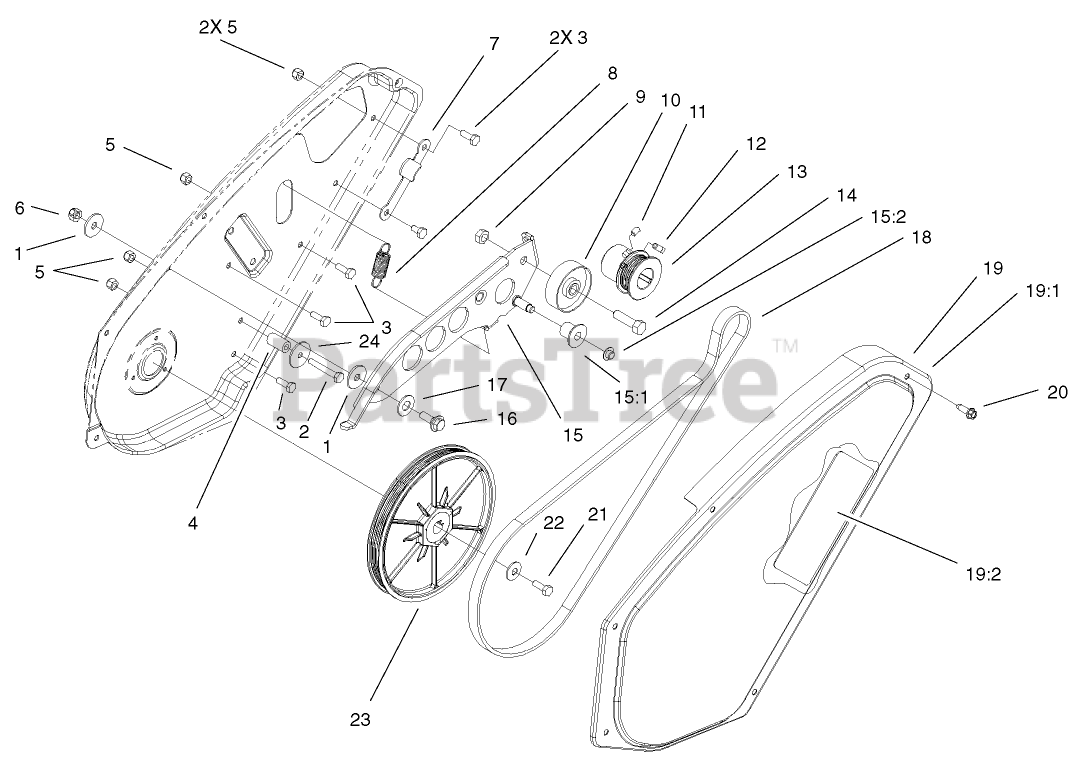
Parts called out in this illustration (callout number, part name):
1	WASHER-PIVOT
2	SCREW-HH
3	SCREW-HH
4	SLEEVE-GUIDE, BELT
5	NUT-LOCK, NI
6	NUT-LOCK, NI
7	BELT-GUIDE
8	SPRING
9	NUT-LOCK, CONE
10	PULLEY-IDLER
11	SCREW-HSH
12	SCREW-SQH
13	PULLEY
14	SCREW-HH
15	BRAKE-ARM
15:1	ROLLER-BRAKE
15:2	NUT-PUSH
16	SCREW-SHOULDER
17	WASHER
18	BELT-DRIVE
19	DRIVE COVER ASM
19	COVER-DRIVE W/DECAL CE
19:1	DECAL-WARNING
19:1	DECAL-HOT
19:2	DECAL-ROUTING, BELT
20	SCREW-HWHTF
21	SCREW-HH
22	WASHER-BELLEVILLE
24	WASHER-FLAT
